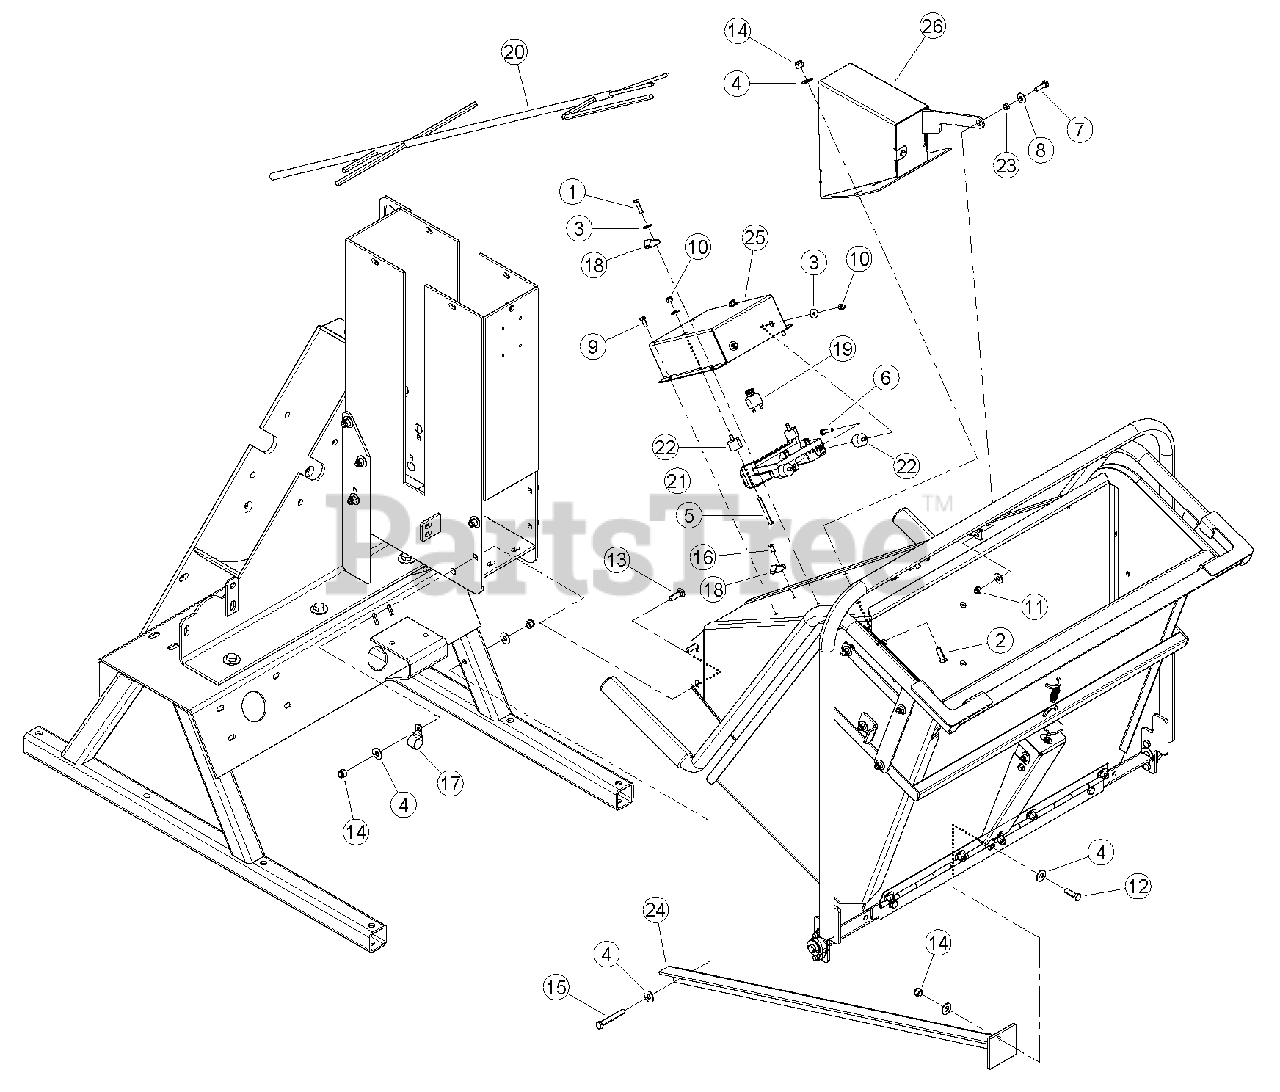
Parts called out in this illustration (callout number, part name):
1	BOLT, 1/4 X 1 HEX GR5 ZP
2	BOLT, 3/8 X 1 HEX GR5 ZP
3	WASHER, 1/4 FLAT ZP
4	WASHER, 3/8 FLAT ZP
5	BOLT, 1/4 X 2-1/4 HEX GR5 ZP
6	BOLT, 1/4 X 1-1/4 HEX GR5 ZP
7	BOLT, 5/16 X 1 HEX GR5 NC ZP
8	WASHER, 5/16 FLAT ZP
9	BOLT, 1/4 X 5/8 HEX GR5 ZP
10	NUT, 1/4 NE NYLOCK ZP
11	NUT, 5/16 NE NYLOCK ZP
12	BOLT, 3/8 X 1-1/4 HEX GR5 ZP
13	BOLT, 3/8 X 1-1/4 CRG GR5 ZP
14	NUT, 3/8 NE NYLOCK ZP
15	BOLT, 3/8 X 2-3/4 HEX GR5 ZP
16	RIVET, AL BLIND 1/4 X 3/4 DOME HEAD
17	CLAMP, 1" COATED METAL
18	CLAMP, CABLE MOUNT
19	CIRCUIT BREAKER, 10 AMP RESETTABLE
20	HARNESS, 5 IN PTO PLUS 1 CONTROLLER
21	CONTROLLER, PLUS 1 CHIPPER
22	BUMPER, 1" OD W/1/4" STUD
23	SPACER, IDLER PIVOT
24	WELDMENT, CHUTE SUPPORT
25	ENCLOSURE, PLUS 1 MOUNT
26	ASSEMBLY, SWITCH BOX
